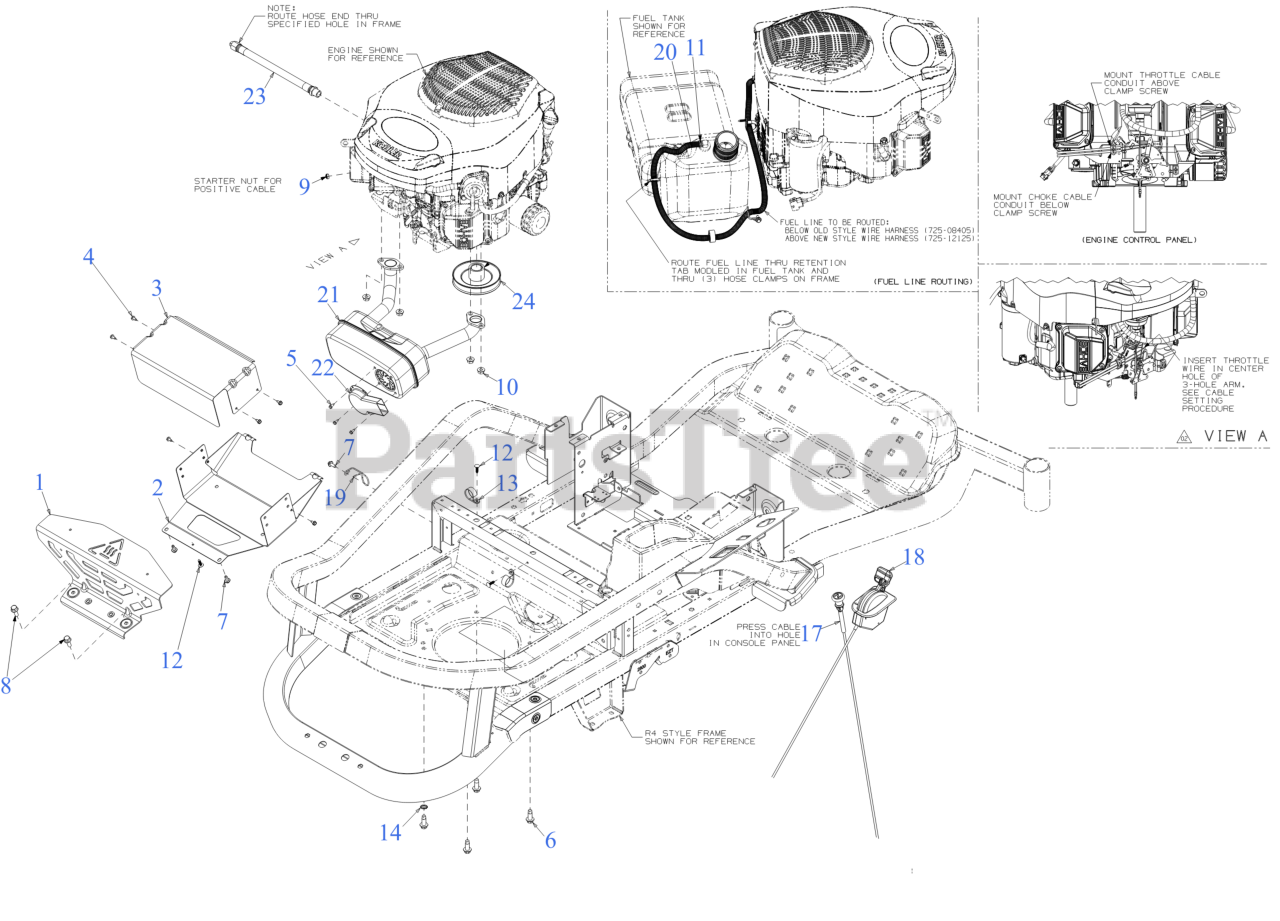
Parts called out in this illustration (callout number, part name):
1	MUFFLER COVER (REAR) (BLACK)
2	MUFFLER SHIELD (LOWER)
3	MUFFLER SHIELD (TOP)
4	HEX SCREW AB-TAP #10 x .50
5	HEX SCREW WASHER HD #8-18 x 0.500
6	SCREW 3/8-16 x 1
7	SCREW M6-1 x .625
8	SCREW 5/16-18 x .875 GR5 HXFLG HD
9	HEX NUT 1/4-20
10	HEX FLANGE NUT M8X
11	HOSE CLAMP 1/20
12	RATCHET CLIP (.188 x .85)
13	DRAIN HOSE CLAMP
14	LOCK WASHER 3/8
17	CHOKE CABLE 51.5LG
18	THROTTLE CABLE 51.0 LG
19	HOSE GUIDE
20	FUEL HOSE LOW PERMEATION 45"
21	EXHAUST MUFFLER (KH TWIN)
22	EXHAUST DELECTOR (LONG)
23	OIL DRAIN HOSE (11.37" 3/8x1/4 NPT)
24	TRANSMISSION DRIVE PULLEY
